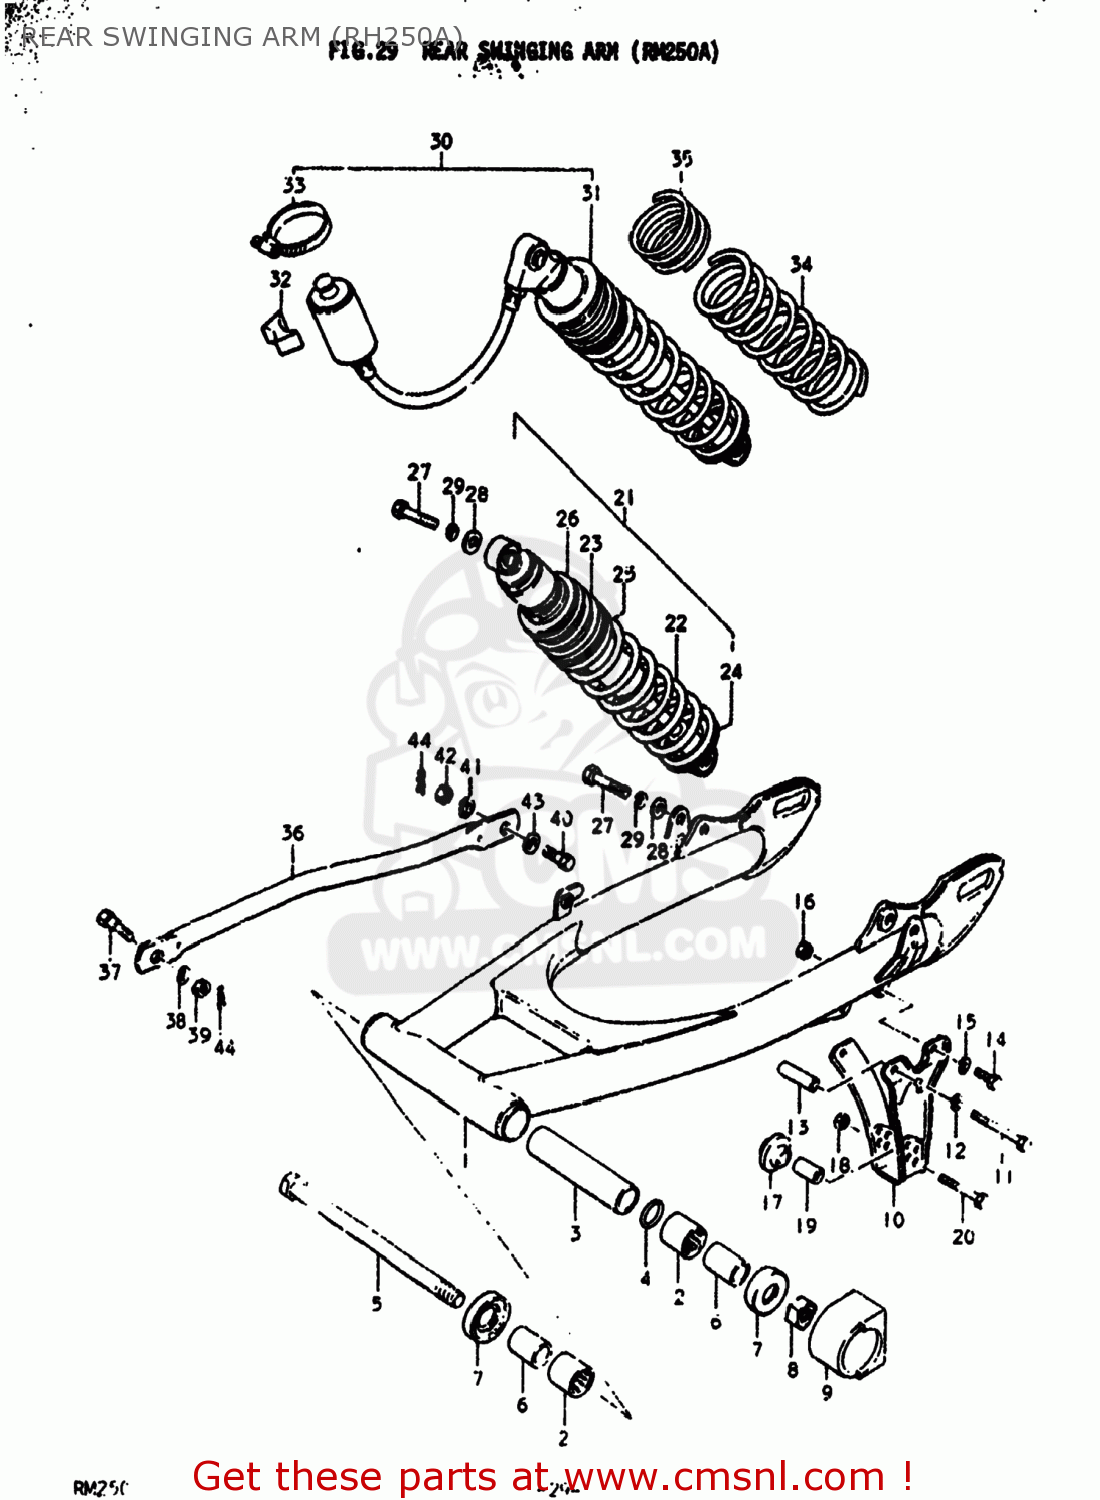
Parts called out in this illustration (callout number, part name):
1	SWING ARM ASSEMBLY,REAR
2	BEARING(20X28X25)
3	SPACER,REAR SWING ARM
4	O RING(D:1.9,ID:18.8)
5	SHAFT,REAR SWING ARM
6	SPACER(14X20X30)
7	THRUST BEARING IKO
8	NUT
9	BUFFER,CHAIN TOUCH DEFLECTOR
10	GUIDE,CHAIN
11	BOLT
12	LOCK WASHER
13	SPACER
14	BOLT, UPPER
15	LOCK WASHER
16	NUT
17	RUBBER,CHAIN GUARD
18	NUT (6MM)
19	SPACER(6.5X10.5X22.5)
20	BOLT
21	ABSORBER ASSEMBLY,REAR SHOCK
22	SPRING
23	SPRING
25	SPRING
26	GUIDE,SPRING
27	BOLT 10X40
28	WASHER
29	LOCK WASHER
30	ABSORBER ASSEMBLY,REAR SHOCK
31	ABSORBER ASSEMBLY,REAR SHOCK
32	CUSHION,RR SHOCK ABSORBER
33	CLAMP
34	SPRING
35	SPRING
36	TORQUE LINK,REAR
37	BOLT(8X22.5)
38	LOCK WASHER
39	NUT
40	BOLT(10X31)
41	LOCK WASHER
42	NUT
43	WASHER
44	CLIP
